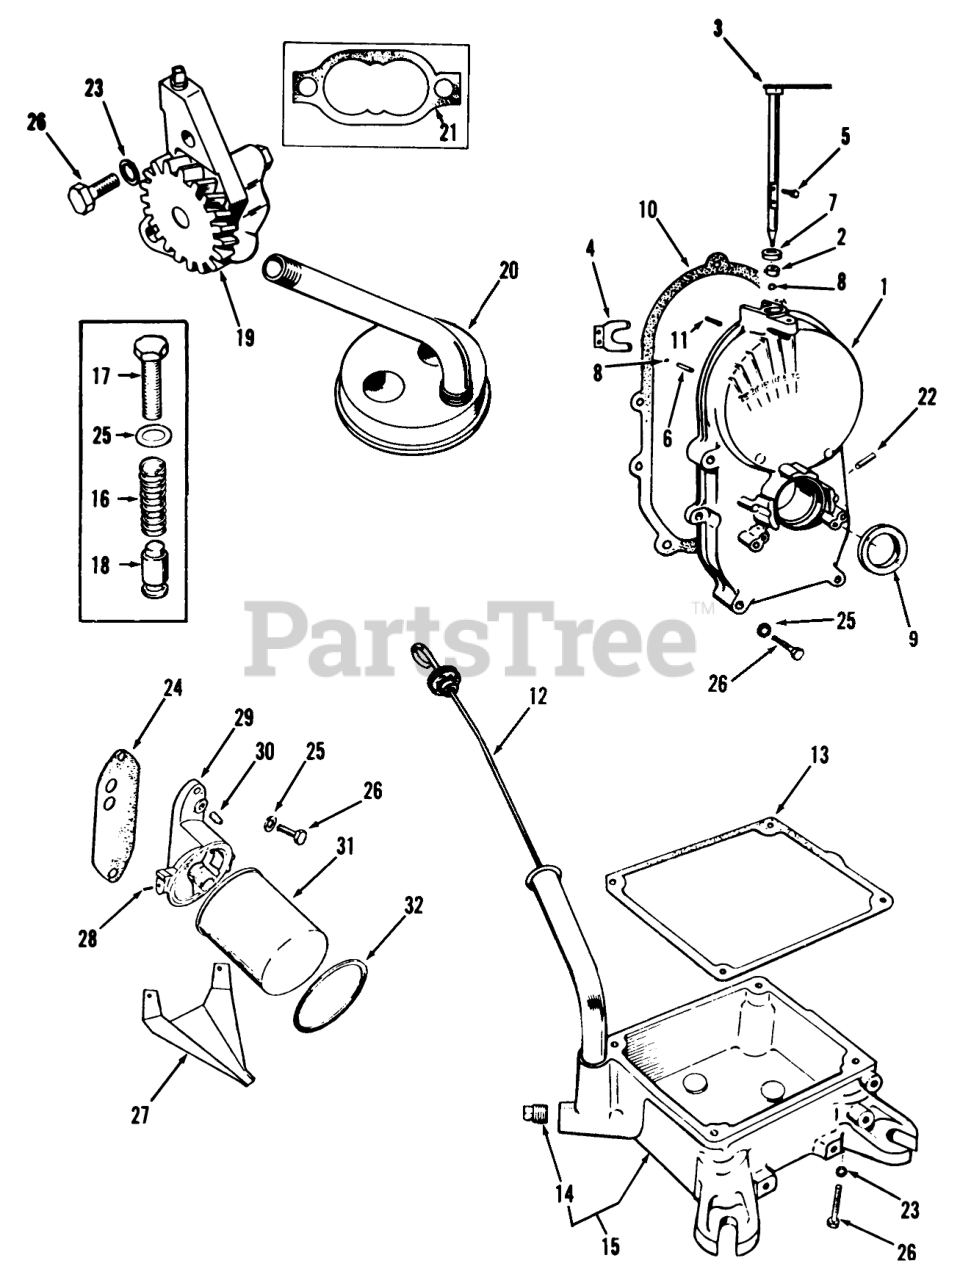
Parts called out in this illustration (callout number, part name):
1	Cover Assy
2	Governor Shaft Bearing
3	Shaft and Arm Assy-Governor
4	Yoke-Governor Shaft
5	Yoke Retaining Screw
6	Pin,Governor-Cup Stop
7	Oil Seal-Governor Shaft
8	Ball Bearing-Governor Shaft
9	Seal-Gear Cover
10	Gasket-Gear Cover Mounting
11	Pin, Gear Cover (5/16 x 1/8)
12	OIL FILL-CAP&INDICTR
13	Oil Base Mounting Gasket
14	Oil Drain Plug
15	Oil Base
16	Spring-Oil By-Pass Valve
17	Screw-Oil By-Pass 3/8-24 X 1
18	Oil By-Pass Valve
19	Oil Pump-Complete
20	Oil Pump Intake Assy
21	Oil Pump Gasket Kit
22	Fuel Pump Vacuum Tube
23	Oil Pump Mounting (1/4")
23	Oil Base Mounting (3/8")
24	Gasket-Oil Filter Pad Cover
25	Copper Washer 5/16 Gear Cover
25	Copper Washer-3/8 Oil Pressure
25	Copper Washer-3/8 Oil Filter
26	Hex Bolt-Oil Filter Adapter
26	Hex Bolt-Oil Pump 1/4-20 X 1
26	Hex Bolt-Gear Cover 2 1/4 Long
26	Hex Bolt-Gear Cover 1 3/4 Long
26	Hex Bolt-Oil Base To Block
27	Dain, Oil Filter
28	Hex HD Screw With Et Washer
29	Oil Filter Adapter
30	Square HD Plug
31	Oil Filter
32	Oil Filter Air Seal
